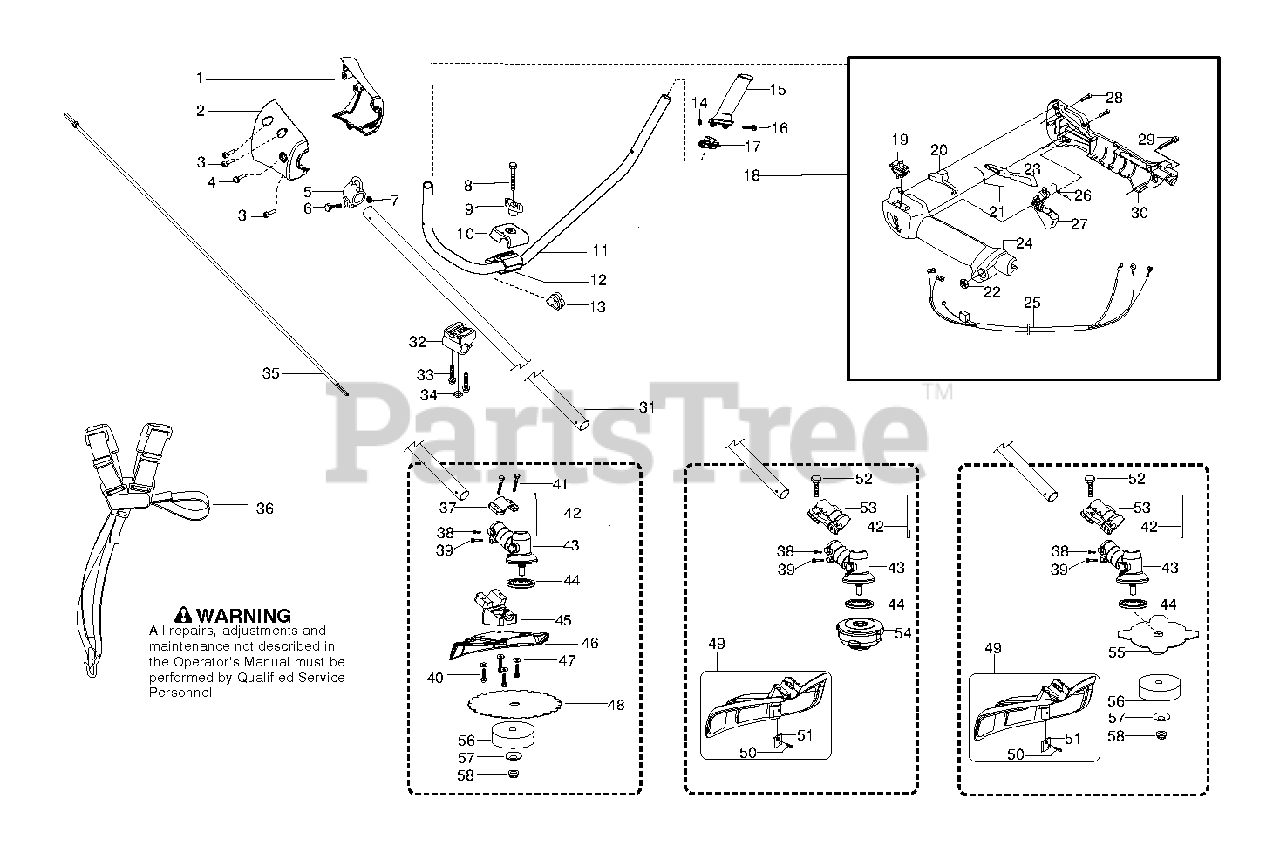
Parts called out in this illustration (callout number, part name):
3	SCREW M4 X 1.75 PT 16MM
4	SCREW-10-16 X 1/2, TYPE 2
12	HOLDER
19	STOP BUTTON
20	STARTER THROTTLE LOC
25	ASSY CABLE WIRE HARNESS
29	%SCREW
41	BOLT FLANGE - M6X20
42	LOCKING PIN
44	DRIVE DISC
46	METAL GUARD 200MM
47	WASHER 5.3X12
51	LINE CUTTER
53	RP BRACKET TRIMMER GUARD
54	T25 TRIM HEAD 10MM LH
55	BLADE GRASS
56	SUPPORTING CUP
57	SUPPORT FLANGE
58	GEARHEAD NUT - BRUSHCUTTER
